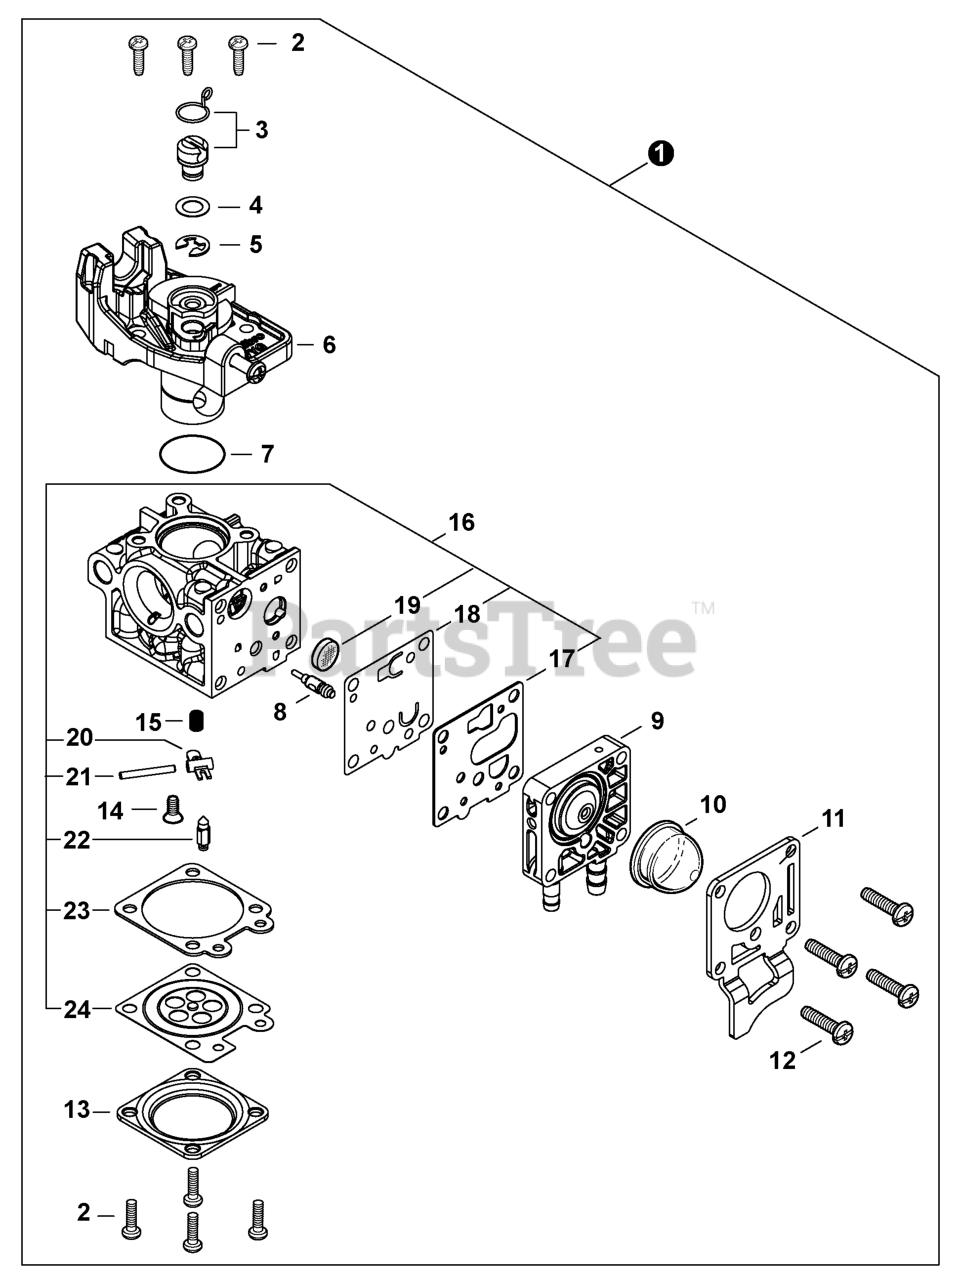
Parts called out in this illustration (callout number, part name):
1	CARBURETOR - WYG-24A
3	SWIVEL KIT
6	THROTTLE VALVE ASSY
8	NEEDLE, MIXTURE
9	BODY ASSY, PUMP
10	BULB, PURGE
11	COVER, FUEL PUMP
13	COVER, METERING DIAPHRAGM
16	REPAIR KIT, CARBURETOR
17	GASKET, FUEL PUMP
18	DIAPHRAGM, FUEL PUMP
19	SCREEN, FUEL INLET
20	VALVE, INLET NEEDLE
21	LEVER, METERING
22	PIN, METERING LEVER
23	GASKET, METERING DIAPHRAGM
24	DIAPHRAGM, METERING
